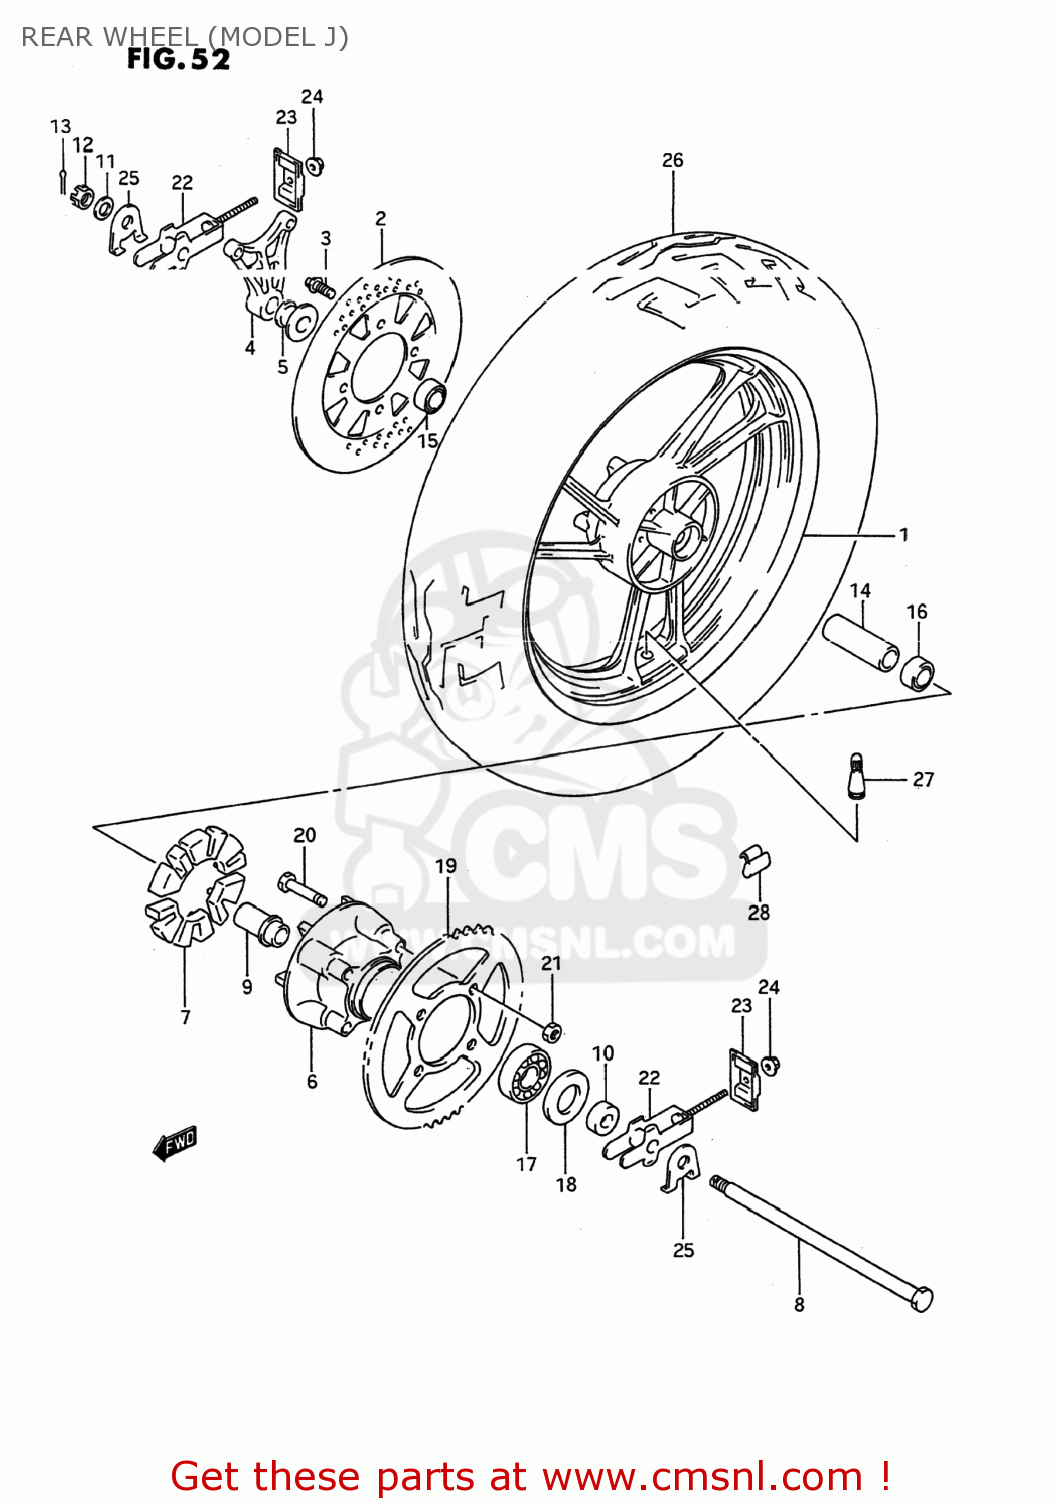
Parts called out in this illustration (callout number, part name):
1	WHEEL,REAR (MT3.00X17)
2	DISC,RR BRAKE
3	BOLT
4	BRACKET,RR,CALIPER
5	SPACER,RR AXLE,R
6	DRUM,REAR SPROCKET MOUNT
7	ABSORBER,RR HUB SHOCK
8	AXLE,REAR
9	RETAINER,RR SPROCKET DRUM
10	SPACER,RR AXLE,L
11	WASHER (17X30X3.2)
12	NUT
13	PIN,COTTER
14	SPACER(17.5X25X81)
15	BEARING
16	BEARING
17	BEARING(25X62X17)
18	SEAL,OIL(35X62X8)
19	SPROCKET,REAR (46T-530)
20	BOLT(10X47)
21	NUT
22	ADJUSTER,CHAIN
23	PLATE,CHAIN ADJUSTER GUIDE
24	NUT
25	WASHER,CHAIN ADJUSTER
26	TIRE
27	VALVE,TIRE
28	BALANCER,WHEEL
